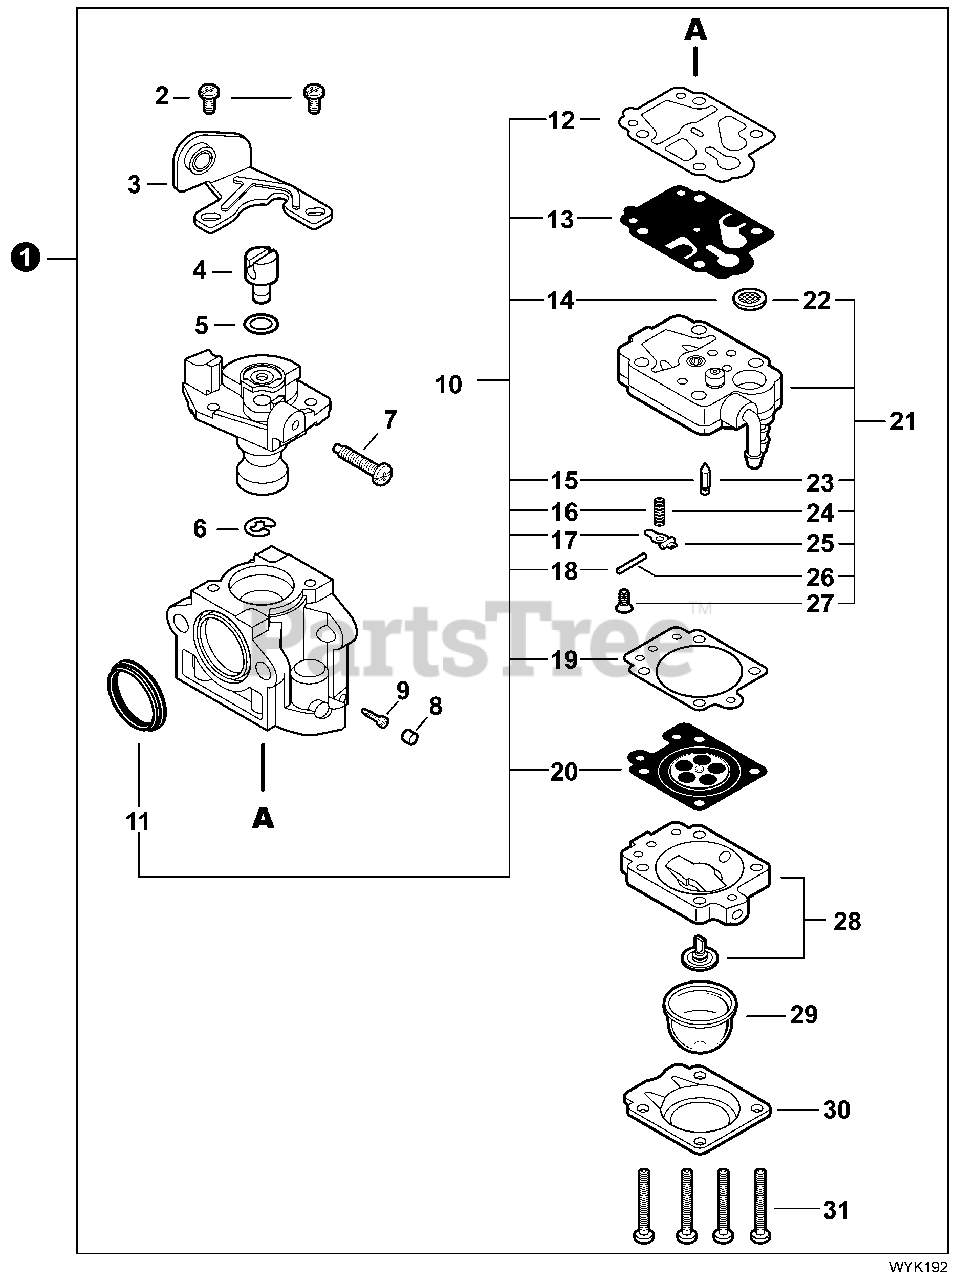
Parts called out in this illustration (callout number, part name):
1	CARBURETOR - WYK-192
3	BRACKET, THROTTLE CABLE
8	CAP, LIMITER
9	NEEDLE, HIGH SPEED
10	REPAIR KIT, CARBURETOR
11	RING, PACKING
12	GASKET, PUMP
13	DIAPHRAGM, PUMP
14	SCREEN, FUEL INLET
15	VALVE, INLET NEEDLE
16	SPRING, METERING LEVER
17	LEVER, METERING
18	PIN, METERING LEVER
19	GASKET, METERING DIAPHRAGM
20	DIAPHRAGM, METERING
21	BODY ASSY, PUMP
22	SCREEN, FUEL INLET
23	VALVE, INLET NEEDLE
24	SPRING, METERING LEVER
25	LEVER, METERING
26	PIN, METERING LEVER
27	SCREW
28	BODY ASSY, PURGE
29	BULB, PURGE
30	RETAINER, PURGE BULB
